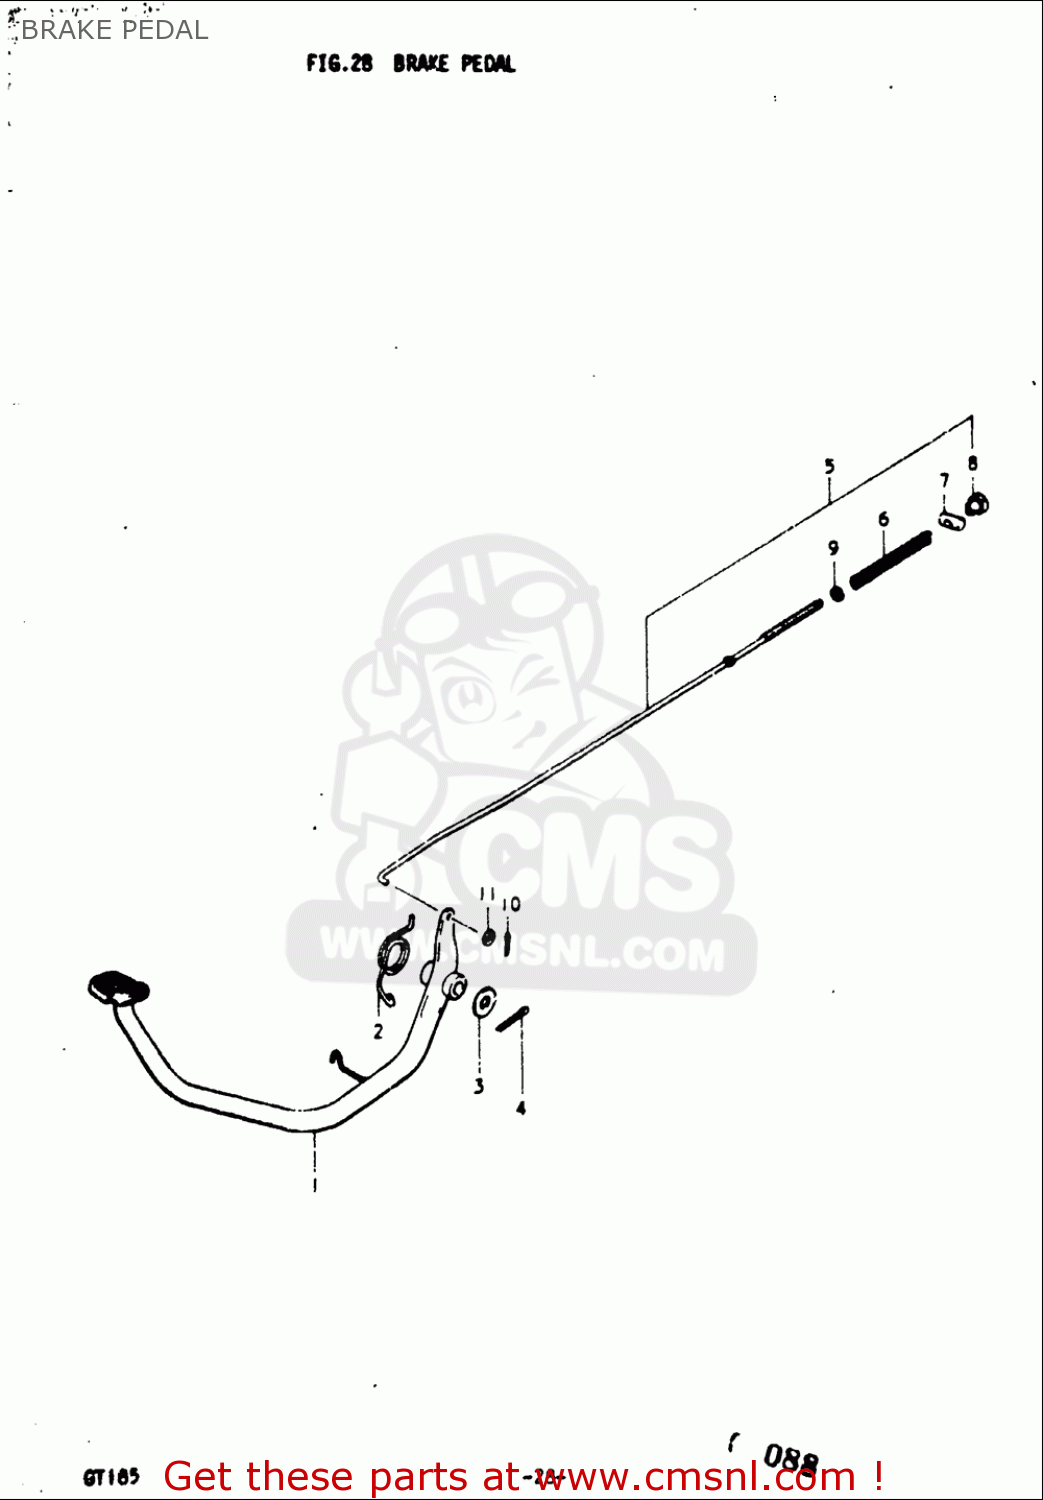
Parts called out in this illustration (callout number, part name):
3	WASHER(15.5X26X2.3)
4	PIN
5	ROD ASSY,RR BRAKE
6	SPRING
7	PIN(11X18)
8	NUT
9	WASHER
10	PIN
11	WASHER
